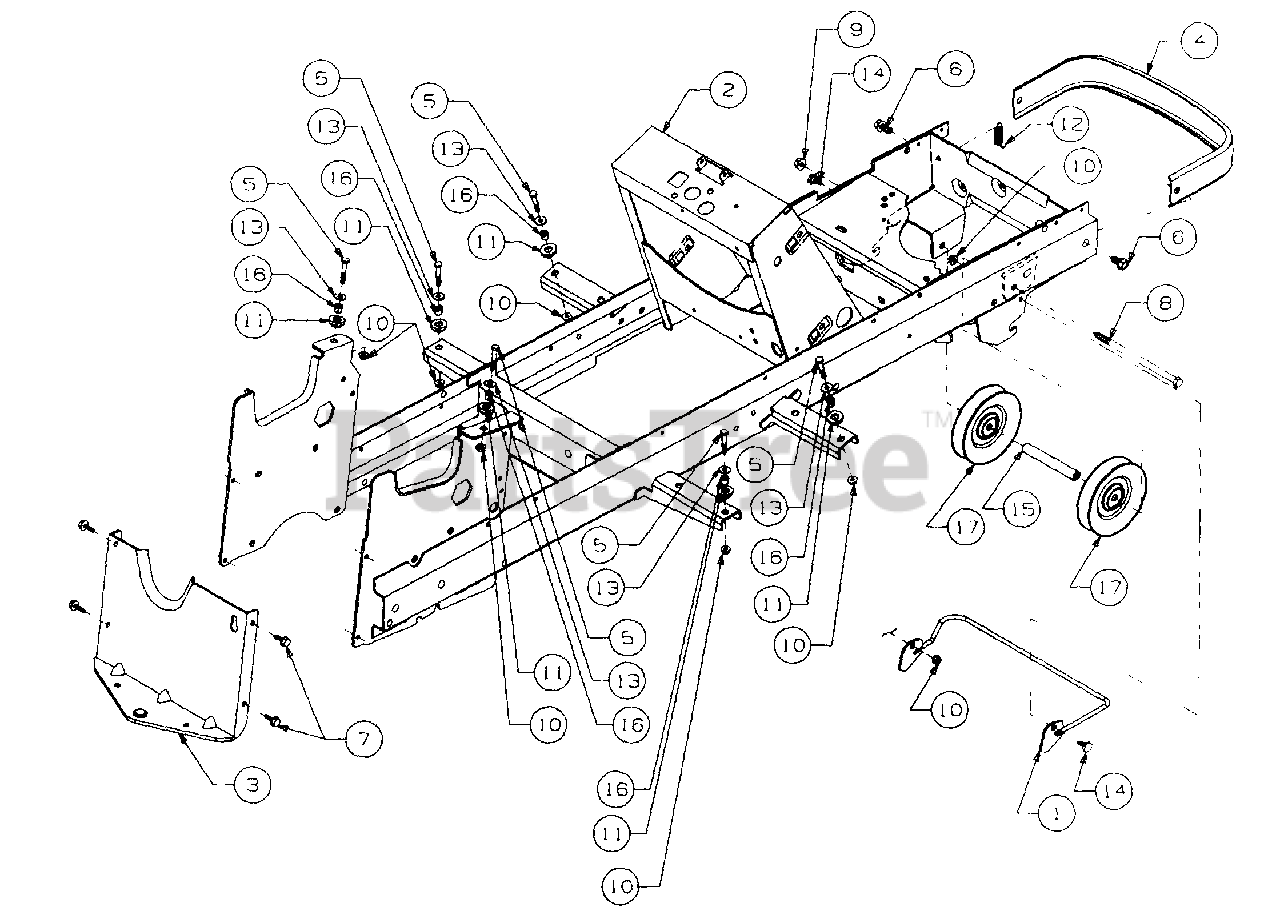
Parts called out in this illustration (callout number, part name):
1	Rod, Quick Attach
2	Frame
3	Drawbar
4	Bumper
5	Screw, Hex Cap, 1/4-20 x 1.0
6	Screw, Hex Wash Hd Tapp 3/8-16 x .75
7	Screw, Hex Wash Hd Tapp 5/16-18 x .75
8	Screw, Hex Cap, 3/8-16 x 7.0
9	Nut, Hex Flange Lock, 3/8-16
10	Nut, Hex Flange Lock, 1/4-20
11	Grommet, Insulator
12	Spring, Latch
13	Washer, Flat, .255 x .72 x .60
14	Bolt, Shoulder
15	Spacer, Idler, .407 x .62 x 4.38
16	Spacer, .28 x .40 x .42 Lg
17	Pulley, Idler
